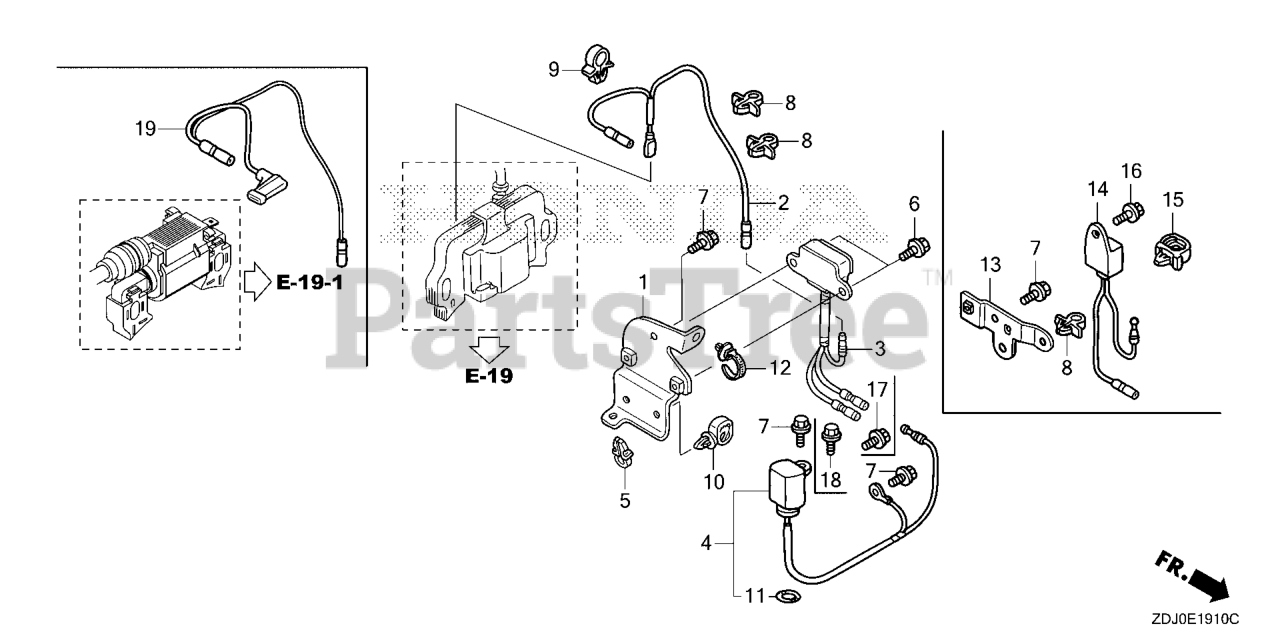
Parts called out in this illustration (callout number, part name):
4	SWITCH ASSY., OIL LEVEL
7	BOLT, FLANGE (6X14)
8	CLIP, CABLE (A)
9	CLIP B, CABLE
11	O-RING (11.8X2.4)
13	BRACKET, OIL ALERT UNIT
14	ALERT UNIT, OIL (CHONGQING LIHUA)
15	CLIP, WIRE HARNESS (10MM)
16	BOLT, FLANGE (6X8)
17	BOLT, FLANGE (6X12) (CT200)
18	BOLT, FLANGE (6X14)
19	WIRE, STOP SWITCH
